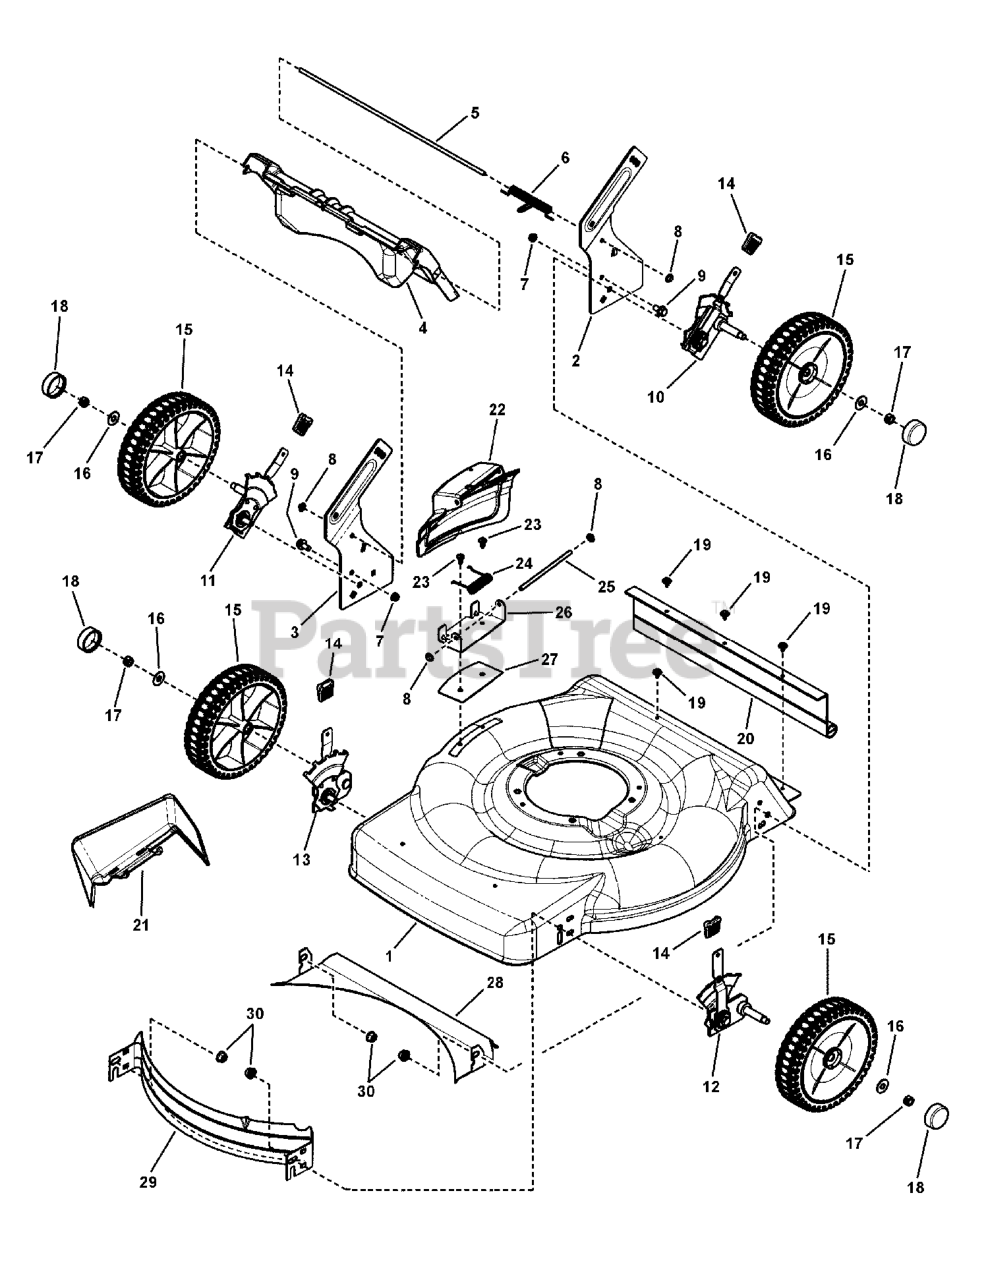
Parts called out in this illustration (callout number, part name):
1	DECK, 22" Walk, Push 3-N-1
2	BRACKET, Lower Handle, LH
3	BRACKET, Lower Handle, RH,
4	DOOR, Rear, 22"
5	ROD, Pivot, Rear Door (1/4"x17.5")
6	SPRING, Torsion, Rear Door, 22" Walk Mower
7	NUT, 5/16-18 Hex Flange Lock BZ
8	PUSHNUT, 1/4"
9	BOLT, 5/16-18 x 5/8" Hex Flange Lock
10	ASSY, Height-of-Cut, 22" WBM, Push, Left Rear (9 Position)
11	ASSY, Height-of-Cut, 22" WBM, Push, Right Rear (9 Position)
12	ASSY, Height-of-Cut, 22" WBM, Push, Right Front (9 Position)
13	ASSY, Height-of-Cut, 22" WBM, Push, Left Front (9 Position)
14	GRIP, Height Latch, Black (Early Models)
14	GRIP, Height Latch, P-391-ST, Yellow
15	WHEEL, 8" x 2" Idle, w/Db Tread, Brute Yellow
16	WASHER, Flat, 1" O.D. x .387 I.D.
17	NUT, 3/8-16 Hex Center Lock YZ
18	HUBCAP, Round, Black
19	SCREW, #10-24 x 1/2" Hex Washer Self-Tap - Sems
20	GUARD, Rear, 22" Deck Mower
21	SIDE CHUTE, Plastic, Black
22	COVER, Mulch, Plastic, Black
23	SCREW, 1/4-20 x .550" Pan Head Self-Tap (Torx)
24	SPRING, Torsion, Chute
25	ROD, Chute Pivot - 1/4" dia. x 5.55"
26	BRACKET, Chute
27	PLATE, Mulch 22" RB Scotts
28	BAFFLE, Rear, 22" Deck
29	BAFFLE, Front, 22" Walk Mower
30	NUT, 3/8-16, Hex Flange Lock, GR 5
